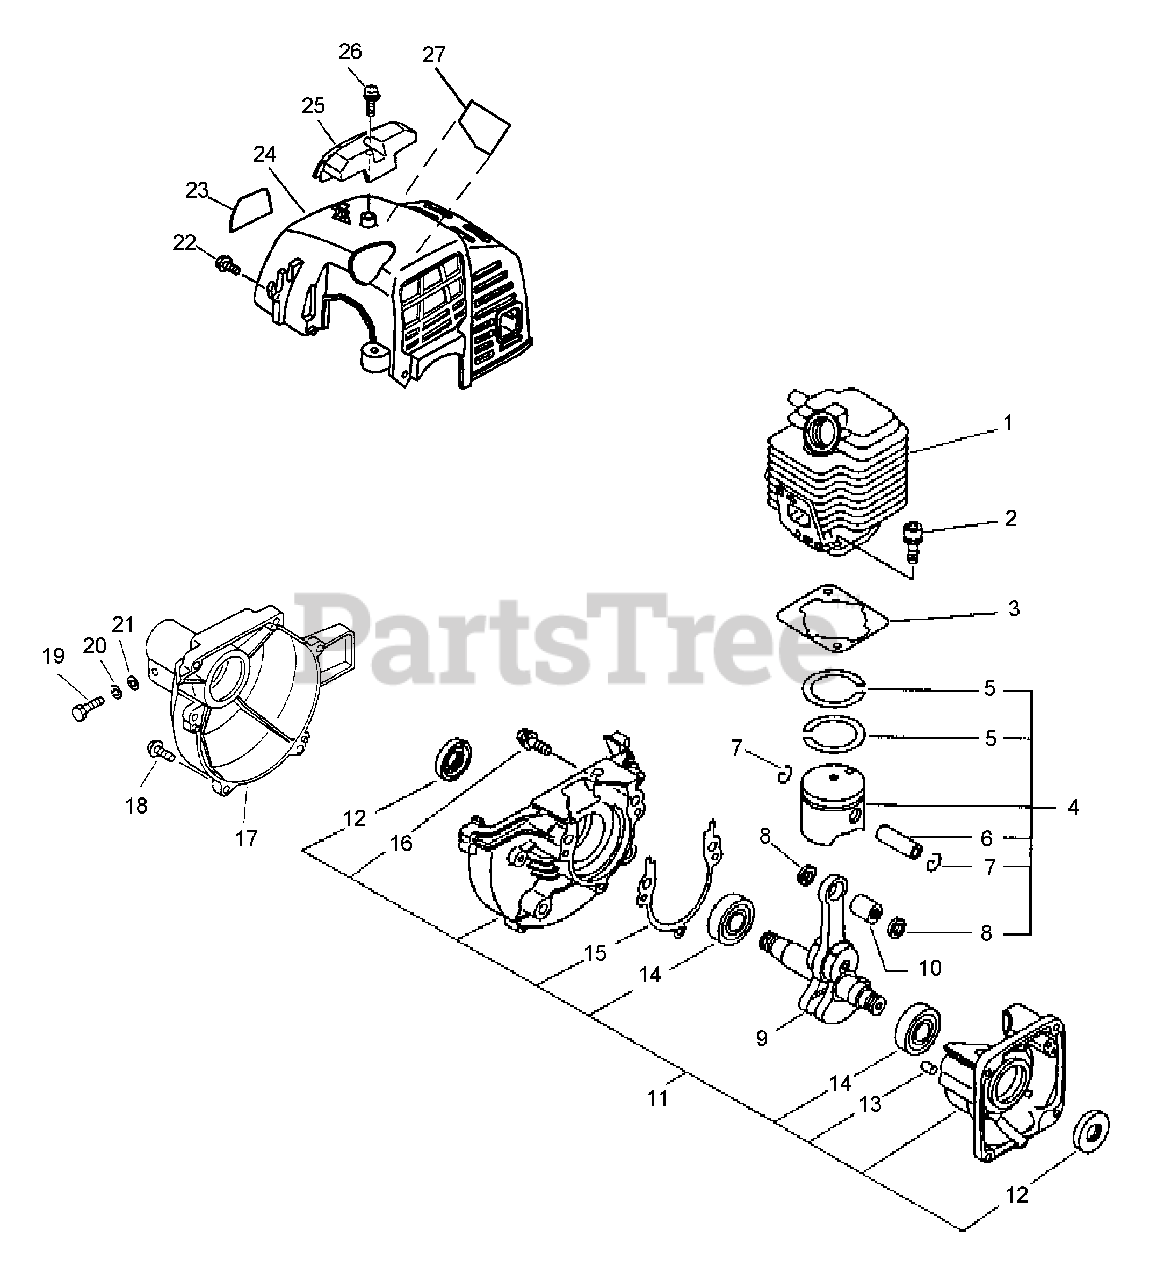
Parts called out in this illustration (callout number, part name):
1	CYLINDER
2	BOLT 5×22
3	GASKET, CYLINDER
4	PISTON KIT
5	RING, PISTON
6	PIN, PISTON 8
7	RING, SNAP
8	WASHER, THRUST
9	CRANKSHAFT ASSY
10	BEARING, NEEDLE
11	CRANKCASE ASSY
12	SEAL, OIL 12
13	PIN, LOCATING 4
14	BEARING, BALL - 6201 C3
15	GASKET, CRANKCASE
16	BOLT 5×28
17	CASE, FAN
18	BOLT 4×16
19	BOLT 5×25
20	WASHER, SPRING 5
21	WASHER, FLAT 5.5×10×0.8
22	SCREW 4×12
23	LABEL - MODEL
24	COVER, ENGINE - ORANGE
25	GUARD, TOP - BLACK
26	SCREW 5×16
27	LABEL, CAUTION
